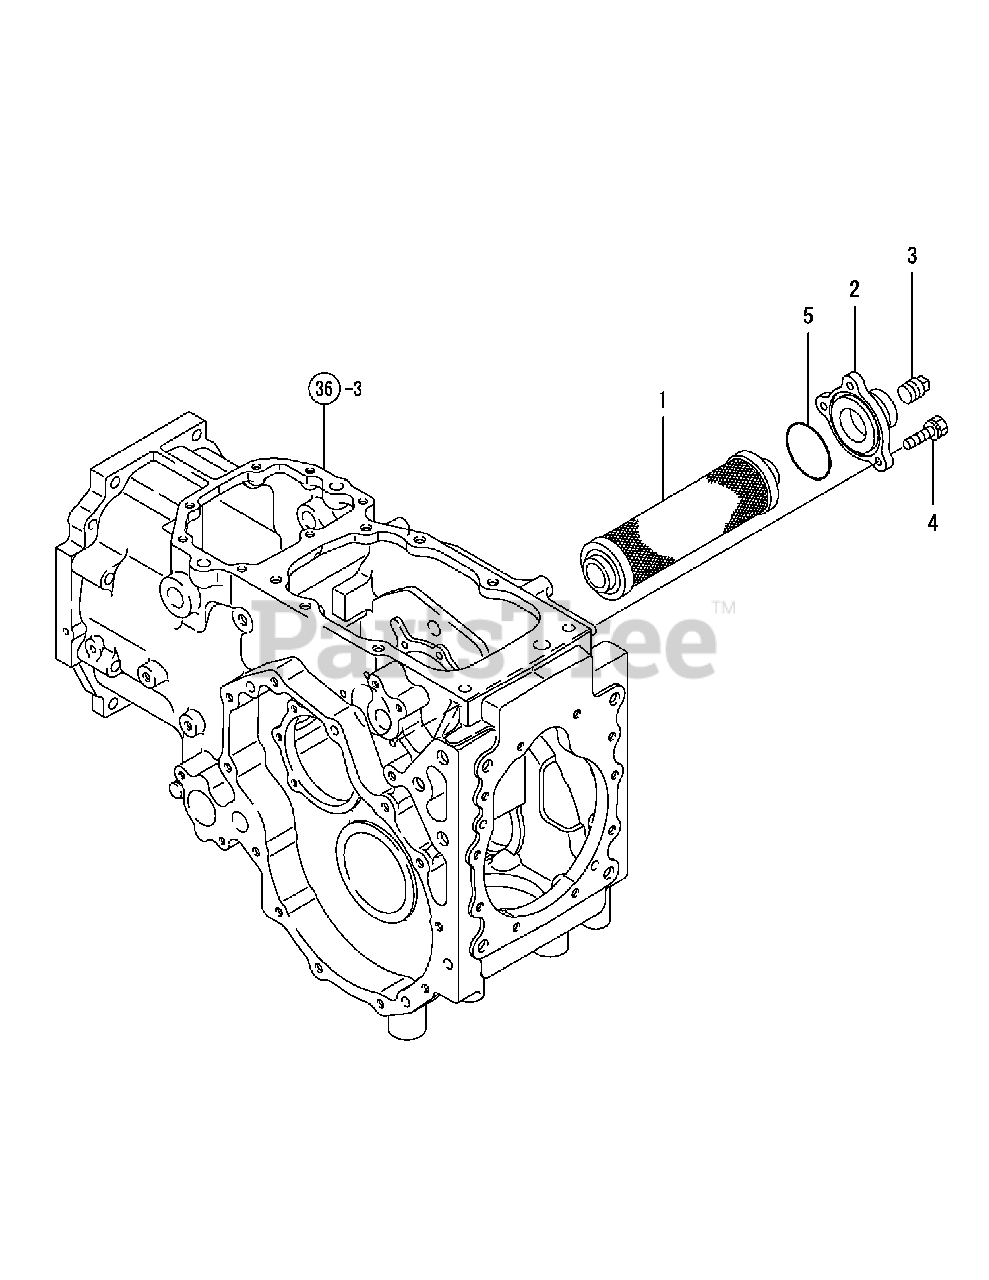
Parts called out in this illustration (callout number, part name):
1	FILTER, SUCTION
2	COVER, OIL STRAINER
4	BOLT M 8X 20 PLATED
5	O-RING 1A G-50.0
